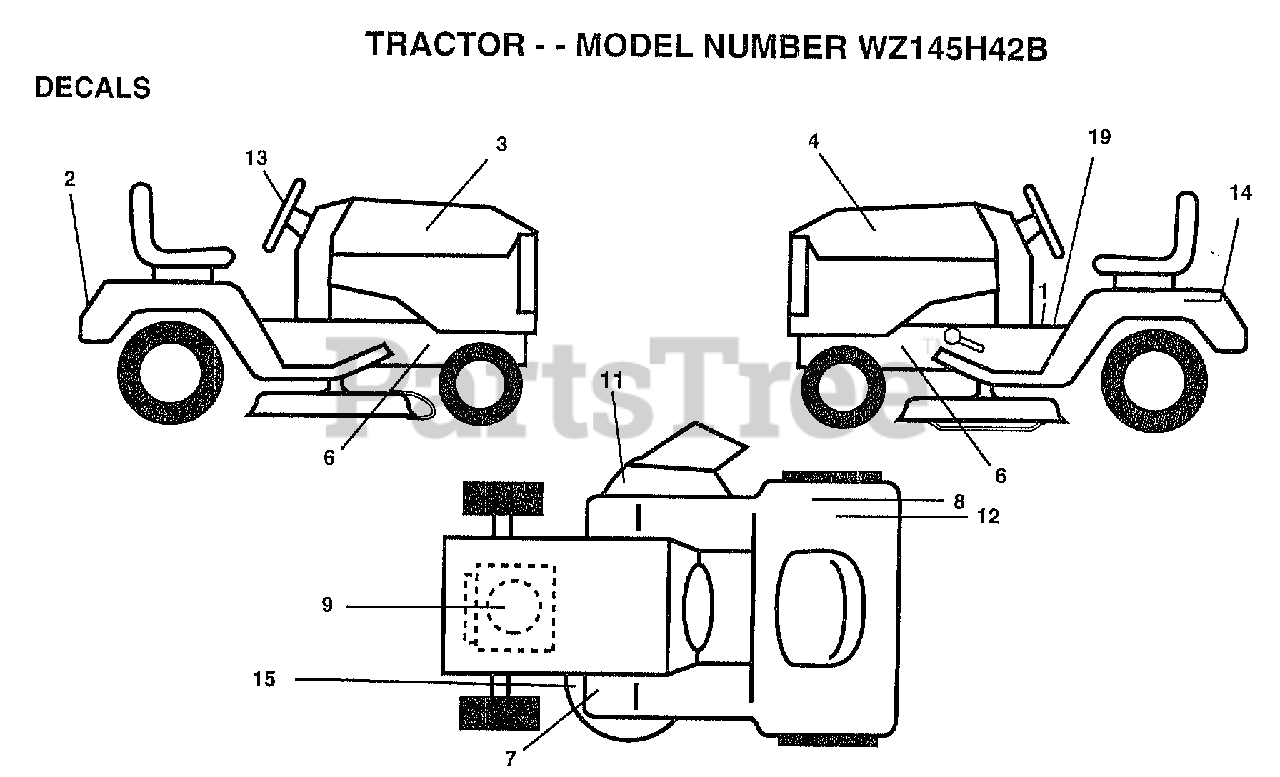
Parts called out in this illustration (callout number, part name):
1	DECAL.READ.O.MANU
2	DECAL.FENDER
3	DECAL.HOOD.RH
4	DECAL.HOOD.LH
6	"DECAL CHASSIS,HOT"
7	DECAL-BRAKE/CLUTC
8	DECAL.EURO.ST.CE.
9	DECAL.ENGINE
11	DECAL.DANGER.CUTF
13	DECAL.INS.STRG/WH
14	DECAL.BATRY.3-3908
15	"DECAL-SCHEM,BELT"
19	DECAL BRAK PARK
